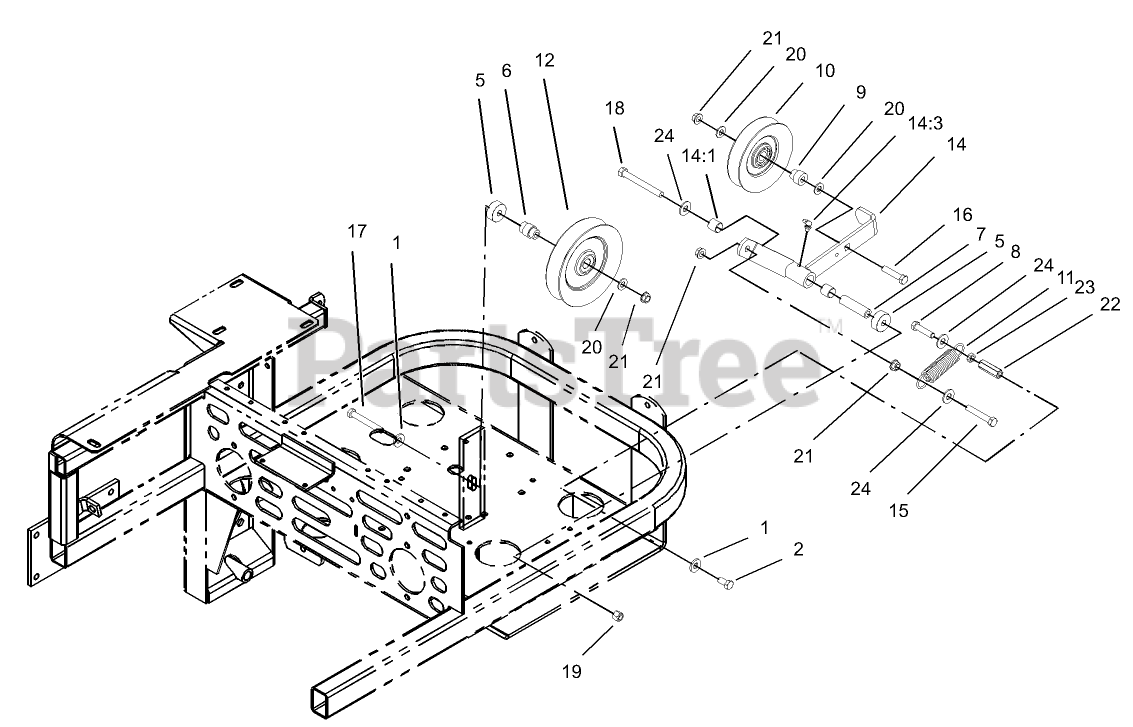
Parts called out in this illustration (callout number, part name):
1	WASHER-BELLEVILLE
2	SCREW-HH
5	Spacer-Idler
6	Bushing-Idler
7	BUSHING-PIVOT, IDLER
8	SCREW-HH
9	BUSHING-IDLER
10	Idler
11	SPRING-EXTENSION
12	PULLEY-IDLER
14	IDLER ARM ASM
14:1	SLEEVE-BEARING
14:3	FITTING-GREASE, 90 DEG
15	SCREW-HH
16	SCREW-HH
17	SCREW-HH
18	SCREW-HH
19	NUT-LOCK, NI
20	WASHER-FLAT
21	NUT-HHF, WHIZ
22	Nut-Coupling
23	NUT-JAM
24	WASHER-FLAT
